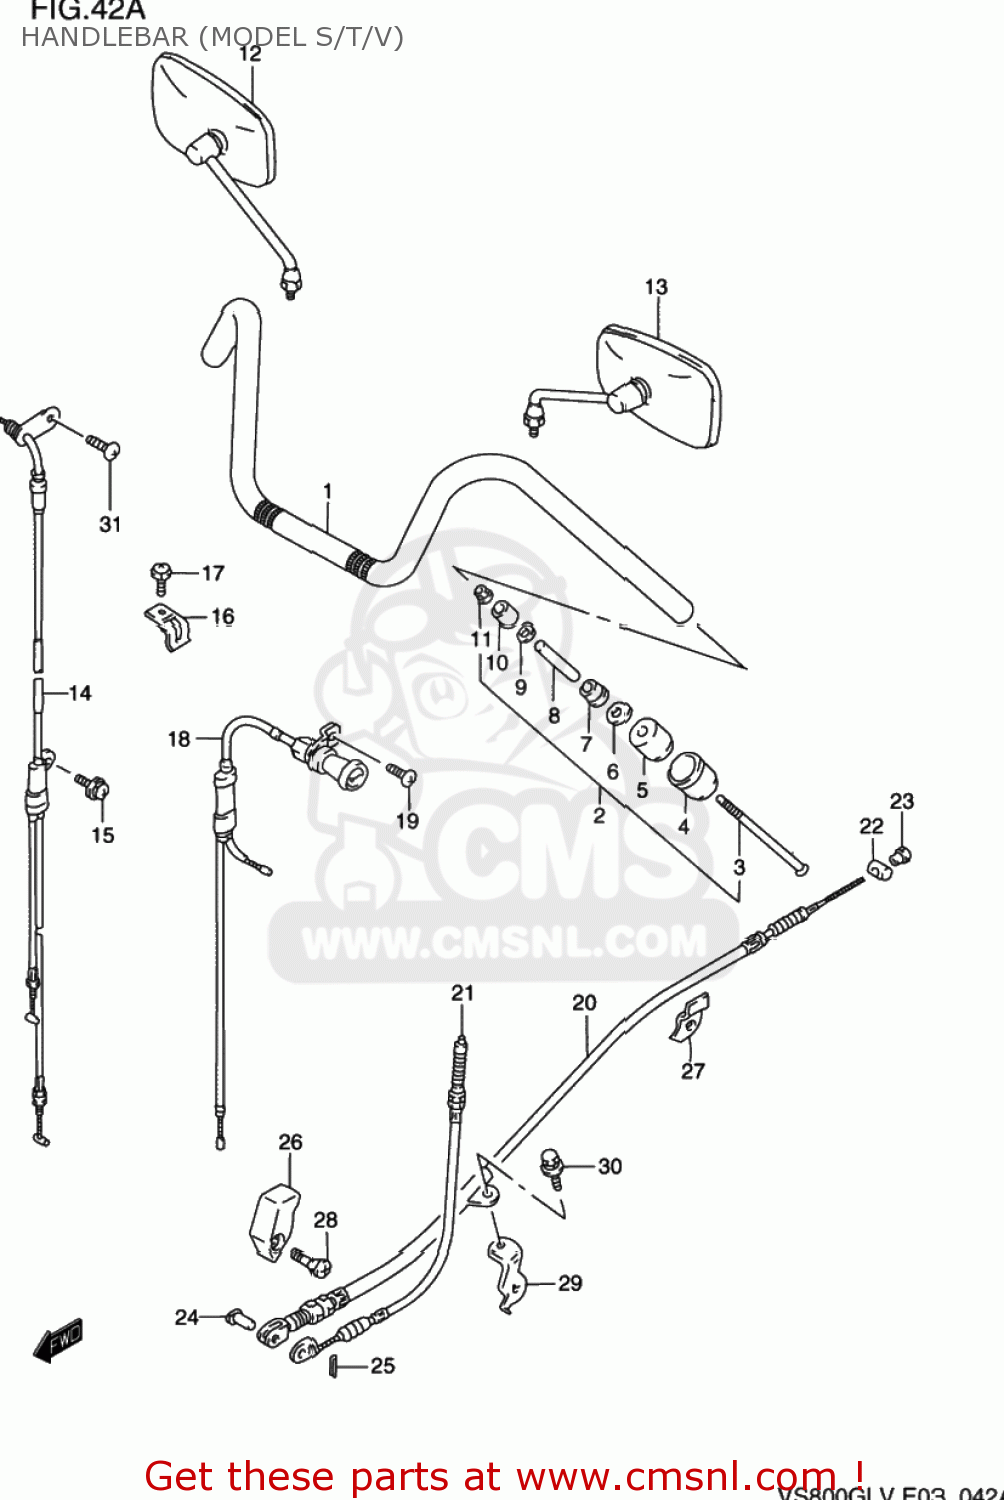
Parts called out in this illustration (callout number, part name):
1	HANDLEBAR
2	BALANCER SET,HANDLEBAR
3	SCREW(6X110)
4	CAP,HANDLE BALANCER
5	BALANCER,HANDLEBAR
6	SPACER,BALANCER
7	EXPANDER,HANDLE BALANCER
8	SPACER,EXPANDER
9	WASHER(6.5X18X1)
10	BALANCER,HANDLEBAR
11	NUT
12	MIRROR ASSY,RR VIEW,R
13	MIRROR ASSY,RR VIEW,L
14	CABLE ASSY,THROTTLE
15	SCREW
16	CLAMP,THROTTLE CABLE
17	SCREW
18	CABLE ASSEMBLY,STARTER
19	SCREW 6X10
20	CABLE,RR BRAKE
21	CABLE,STOP LAMP SWITCH
22	PIN
23	NUT
24	PIN(L:17.5)
25	PIN
26	GUIDE,RR BRAKE CABLE
27	CLAMP,RR BRAKE CABLE
28	SCREW
29	BRACKET,RR BRAKE CABLE
30	BOLT
31	SCREW
